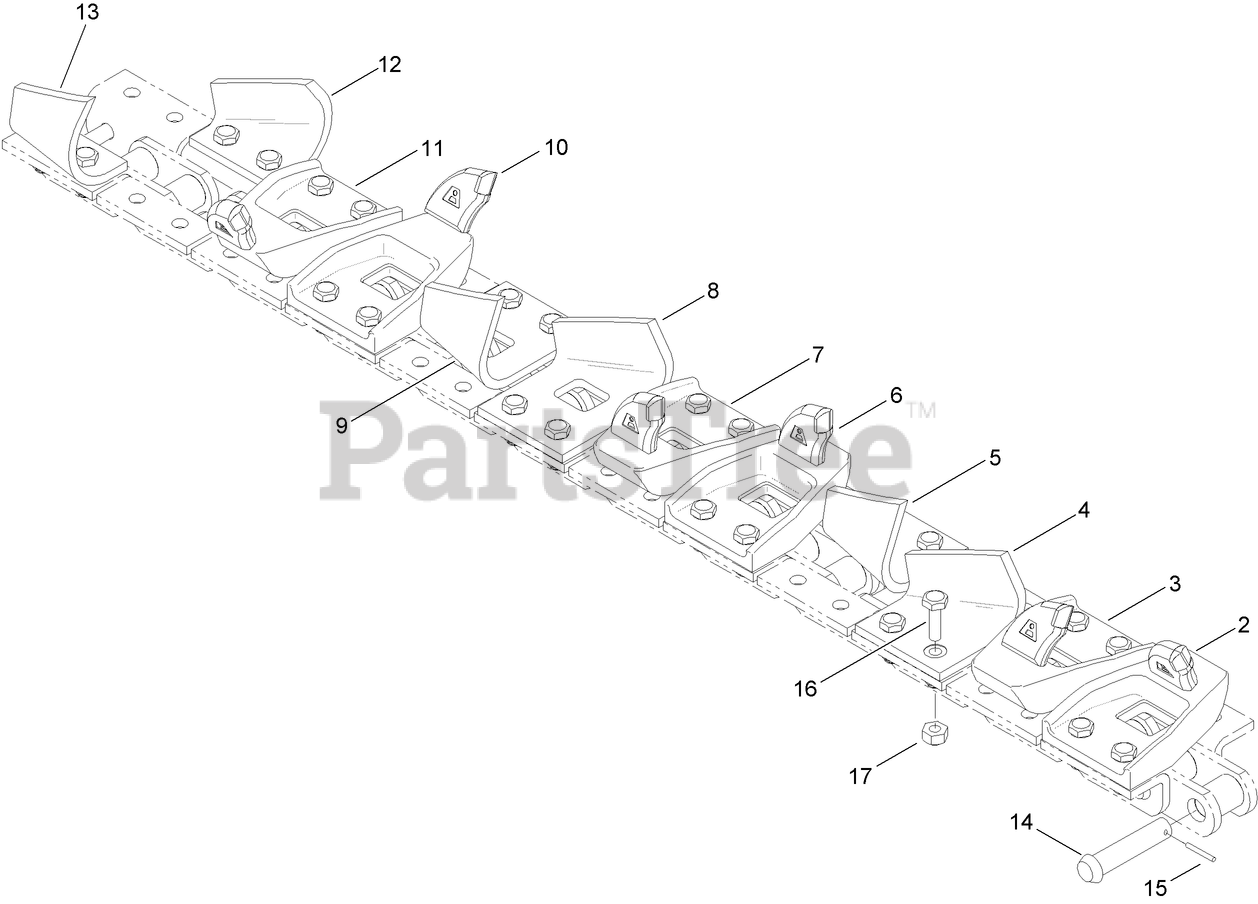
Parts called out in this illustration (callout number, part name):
2	TOOTH-SHARK (1" L)
3	TOOTH-SHARK (1" R)
4	TOOTH-CUP (1"-8" L)
5	TOOTH-CUP (1"-8" R)
6	TOOTH-SHARK (3" L)
7	TOOTH-SHARK (3" R)
8	TOOTH-CUP (3" L)
9	TOOTH-CUP (3" R)
10	TOOTH-SHARK (6" L)
11	TOOTH-SHARK (6" R)
12	TOOTH-CUP (6" L)
13	TOOTH-CUP (6" R)
14	PIN-MASTER
15	PIN-KEEPER, MASTER
17	NUT-LOCK
